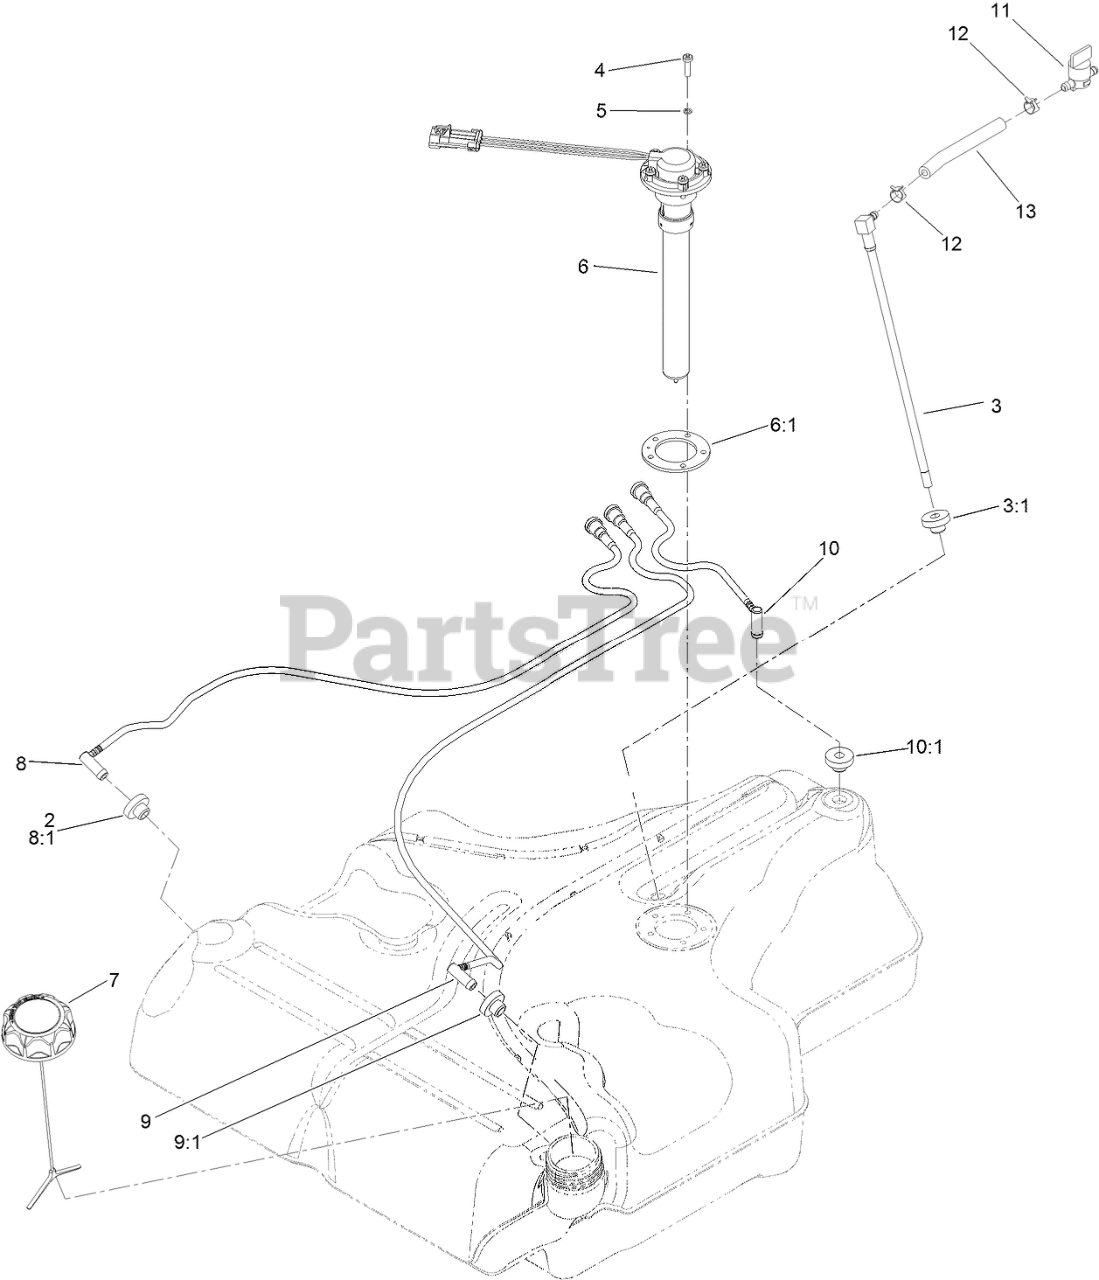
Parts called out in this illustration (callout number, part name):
2	BUSHING
3	FUEL LINE KIT (WITH GROMMET)
3:1	BUSHING
4	SCREW-PPH
5	WASHER-LOCK
6	FLOAT-SENDER, FUEL
6:1	Gasket-Sender
7	CAP-FUEL, RATCHETING
8	RH VENT LINE KIT (WITH GROMMET)
8:1	BUSHING
9	LH VENT LINE KIT (WITH GROMMET)
9:1	BUSHING
10	REAR VENT LINE KIT (WITH GROMMET)
10:1	BUSHING
11	VALVE-FUEL
12	CLAMP-HOSE
13	HOSE-FUEL
